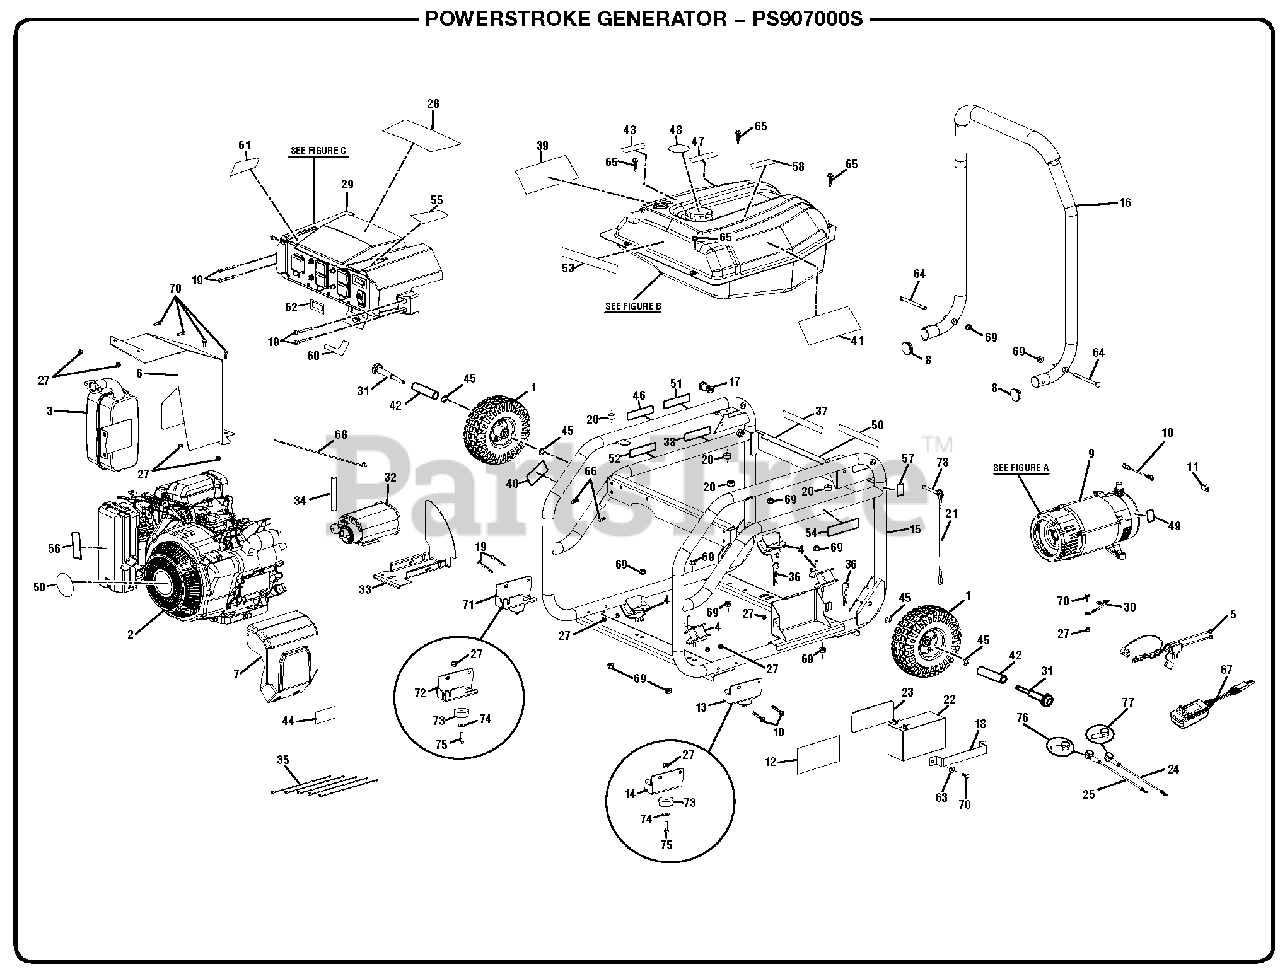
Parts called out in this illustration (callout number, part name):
1	Wheel (10 in. x 3 in.)
3	Muffler (Ducar)
4	Vibration Isolator
5	Pigtail (DC)
6	Heat Shield
7	Engine Starter Cover
9	Generator Head Assembly (See Figure A)
10	Bonding Wire
11	Ground Lug
12	Rubber Sheet
13	Foot Assembly (Left)
14	Foot Bracket (Left)
15	Frame Assembly
16	Handle Assembly
17	Release Pin Assembly
18	Battery Bracket Assembly w/Gasket
19	Bolt (M6 x 50 mm, T30 Torx Pan Hd.)
20	Handle Bumper
21	Handle Lock Pin
22	Battery Bracket
23	Battery Tray Gasket
24	Battery Cable (Red)
25	Battery Cable (Black)
26	Washer (M4)
27	Lock Nut (M6 x 1 mm)
28	Performance Label
29	Control Panel Assembly
30	Ground Wire Assembly
32	Carbon Cannister Assembly
33	Carbon Canister Bracket
34	Purge Hose (100 mm)
36	Hitch Pin
37	Inquiries Label
38	Combustion Label (Eng/Sp)
39	CPSC Label (Eng/Sp)
40	Warning Hang Tag (Eng/Sp)
41	Icon Warning Label
42	Axle Spacer
43	E85 Label
44	Electric Start Label
45	Washer (1/2 in.)
46	Fire Distance Label (En/Sp)
47	Fire Danger Label.
48	Fuel Stabilizer Label (Eng)
49	Ground Label
50	Ground Warning Label
51	Handle Release Label (Eng/Sp)
52	Hot Surface Label
53	Logo Label (Left)
54	Lubricant Label
55	Logo Label
56	Start Label
57	Release Pin Label
58	Fuel Stabilizer Label (Sp)
59	Recoil Label
60	Fuel Valve Label
61	Logo Label (Right)
62	4 in 1 Digital Meter Label
63	Washer (OD17 x ID6.4 x 1.6t)
64	Bolt (M8 x 98 mm, Flat Hd.)
65	Screw (1/4-14 x 1.25 in., Hex Flange Hd.)
66	Bolt (M6 x 16 mm, Hex Hd.)
67	Ritar Battery Charger
68	Cable Tie (495 mm)
69	Flange Lock Nut (M8 x 1.25 in)
70	Bolt (M6 x 16 mm, Hex Hd.)
71	Foot Assembly (Right)
72	Foot Bracket (Right)
75	Bolt (M6 x 20 mm, Hex Hd.)
76	Rubber Battery Cable Boot (Black)
77	Rubber Battery Cable Boot (Red)
